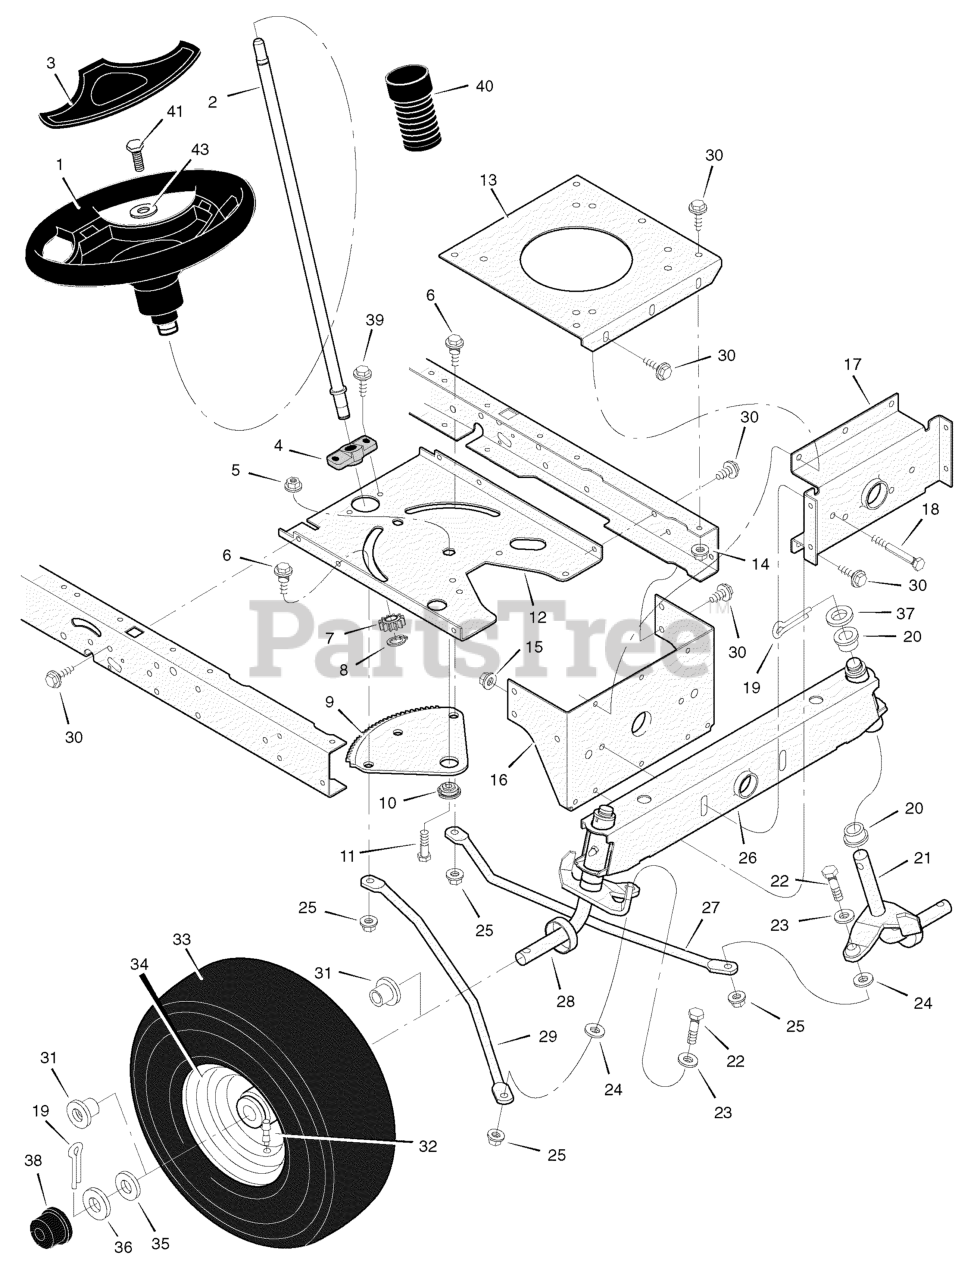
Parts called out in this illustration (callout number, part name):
1	Wheel, Steering
2	Post, Steering
3	Cover, Steering Wheel
4	Bearing
5	Nut, Flange
6	Bolt, Shoulder
7	Gear, Pinion
8	Ring, Snap
9	Gear, Sector
10	Bearing
11	CAPSCREW, Hex Head, 5/16-18 x 1
12	Plate, Steering
13	Plate, Engine
14	Nut, Flange
15	Nut, Flange
16	Bracket, Hanger
17	Axle, Hanger
19	Pin, Cotter
20	Bearing
21	Spindle Assembly, Left
22	Bolt
23	Washer
24	Washer
25	Nut, Flange
26	Axle Assembly
27	Drag Link, Left
28	Spindle Assembly, Right
29	Drag Link, Right
31	Bearing, Wheel
32	Stem, Valve
33	Tire *
34	Wheel andTire Assembly
38	Hub Cap
40	Bellows
41	Screw, Hex
43	Washer
